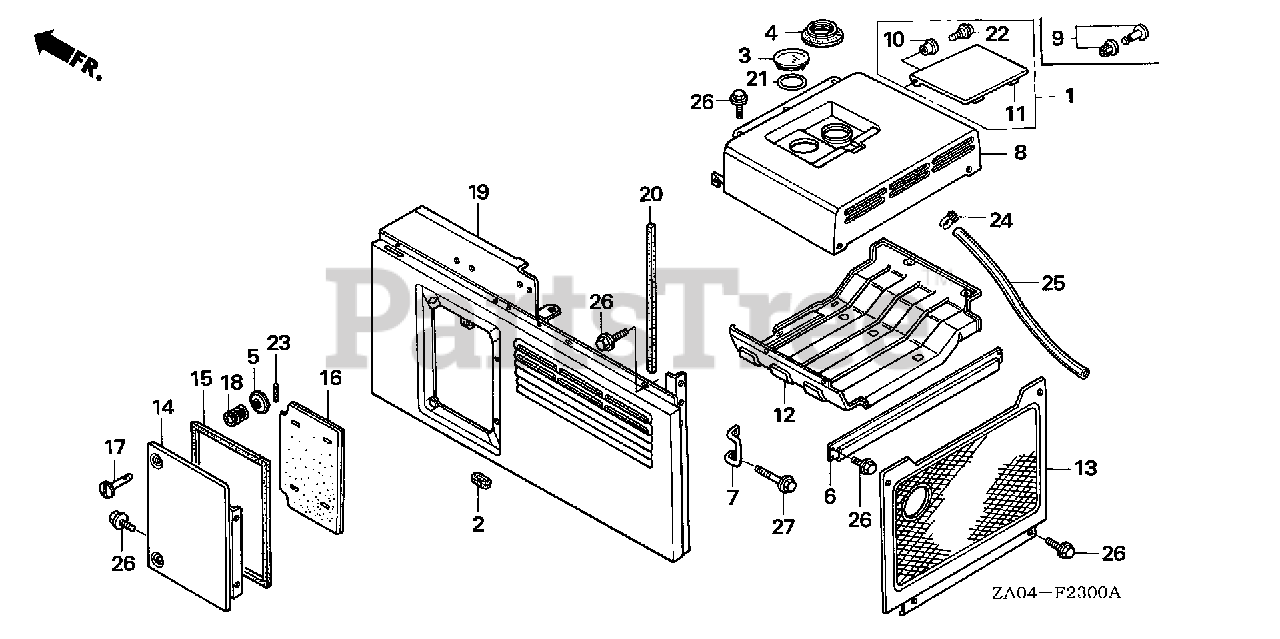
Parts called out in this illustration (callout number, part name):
1	COVER SET, FUEL CAP *NH35M* (CLOUD SILVER METALLIC)
2	GROMMET A, AIR CLEANER HOUSING
3	CAP, FUEL METER
4	SEAL, FUEL FILLER NECK
5	RETAINER, LOCK SPRING
6	HANDLE, RR. *NH105* (MAT BLACK)
7	HOOK, RR. (UPPER)
8	COVER, FUEL TANK (UPPER) *NH35M* (CLOUD SILVER METALLIC)
9	HINGE, FUEL CAP COVER
10	BUSH, FUEL CAP COVER (NOT AVAILABLE)
11	COVER SET, FUEL CAP *NH35M* (CLOUD SILVER METALLIC)
12	COVER, FUEL TANK (LOWER)
13	COVER, RR. *B9* (ATLANTIS BLUE)
14	COVER, CARBURETOR *B9* (ATLANTIS BLUE)
15	RUBBER, CARBURETOR COVER SEAL
16	INSULATOR, CARBURETOR COVER
17	PIN, COVER LOCK
18	SPRING, COVER LOCK
19	COVER, L. SIDE *B9* (ATLANTIS BLUE)
20	RUBBER, SIDE COVER SEAL
21	O-RING (56X2.4)
22	SCREW, PAN (5X12)
23	PIN, SPRING (3X18)
24	CLIP, TUBE (A16)
25	BULK HOSE, VINYL (12X16X3000) (12X16X850)
26	BOLT, FLANGE (6X10)
27	BOLT, FLANGE (6X28)
